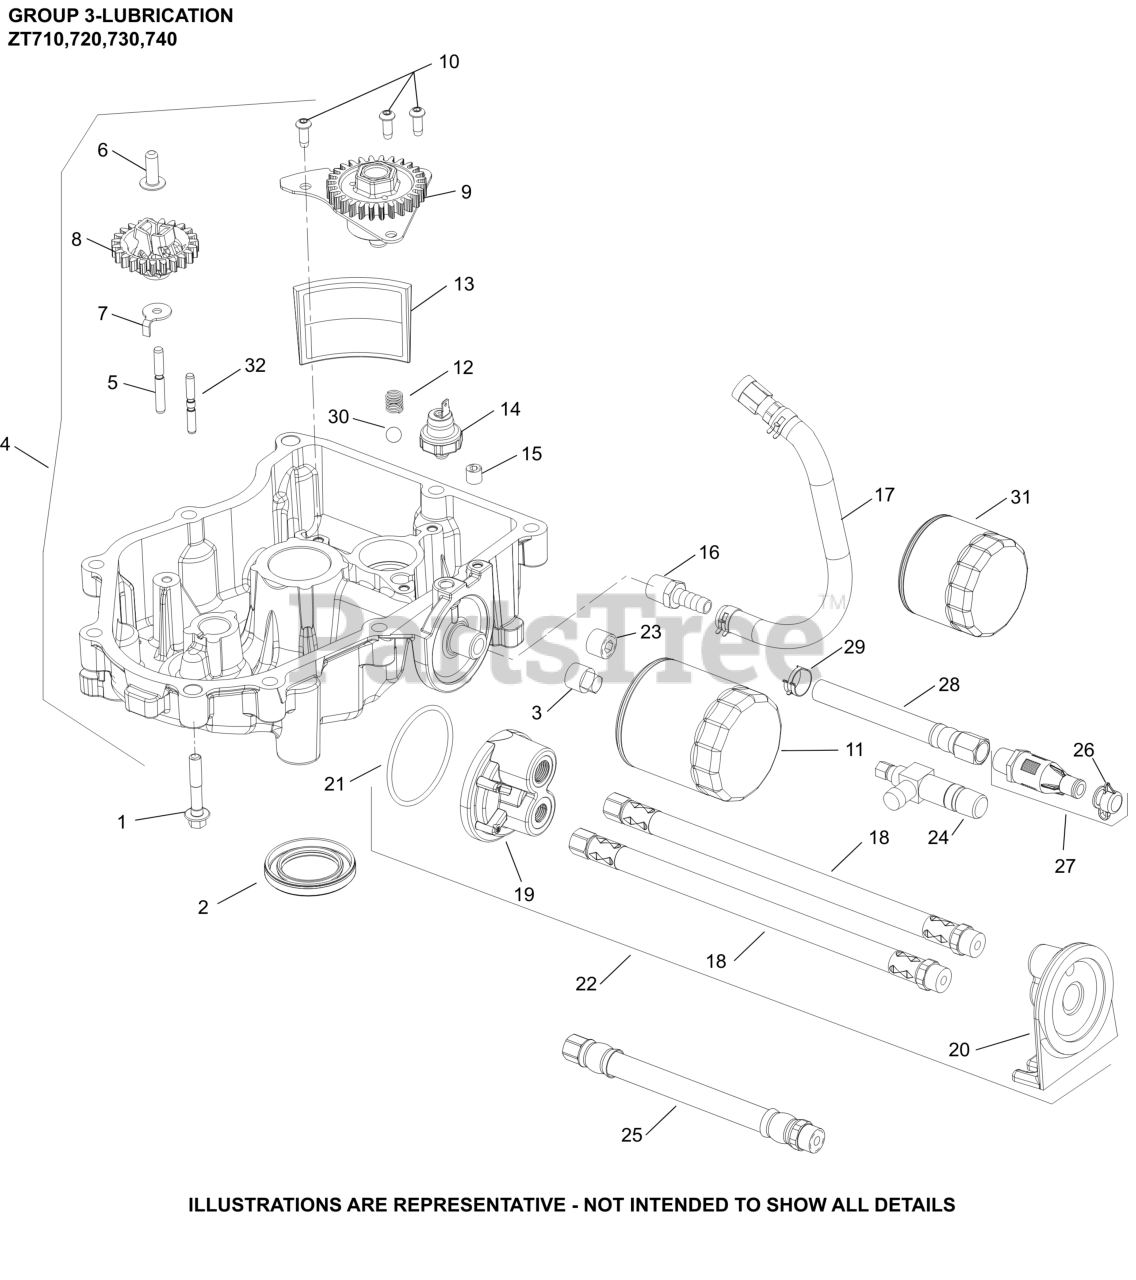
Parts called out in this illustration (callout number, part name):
1	SCREW, FLG M8X1.25X45
3	PLUG, SQ HD PIPE 3/8"
6	PIN, GOVERNOR REGULATING
7	TAB, LOCKING
8	KIT, GOVERNOR GEAR
9	PUMP ASSEMBLY, OIL
10	SCREW, BUTTON HEAD
11	OIL FILTER
12	SPRING, COMPRESSION
13	SCREEN, OIL
14	SENSOR, OIL PSI
30	PRESSURE RELIEF BALL
32	SHAFT, GOVERNOR GEAR
